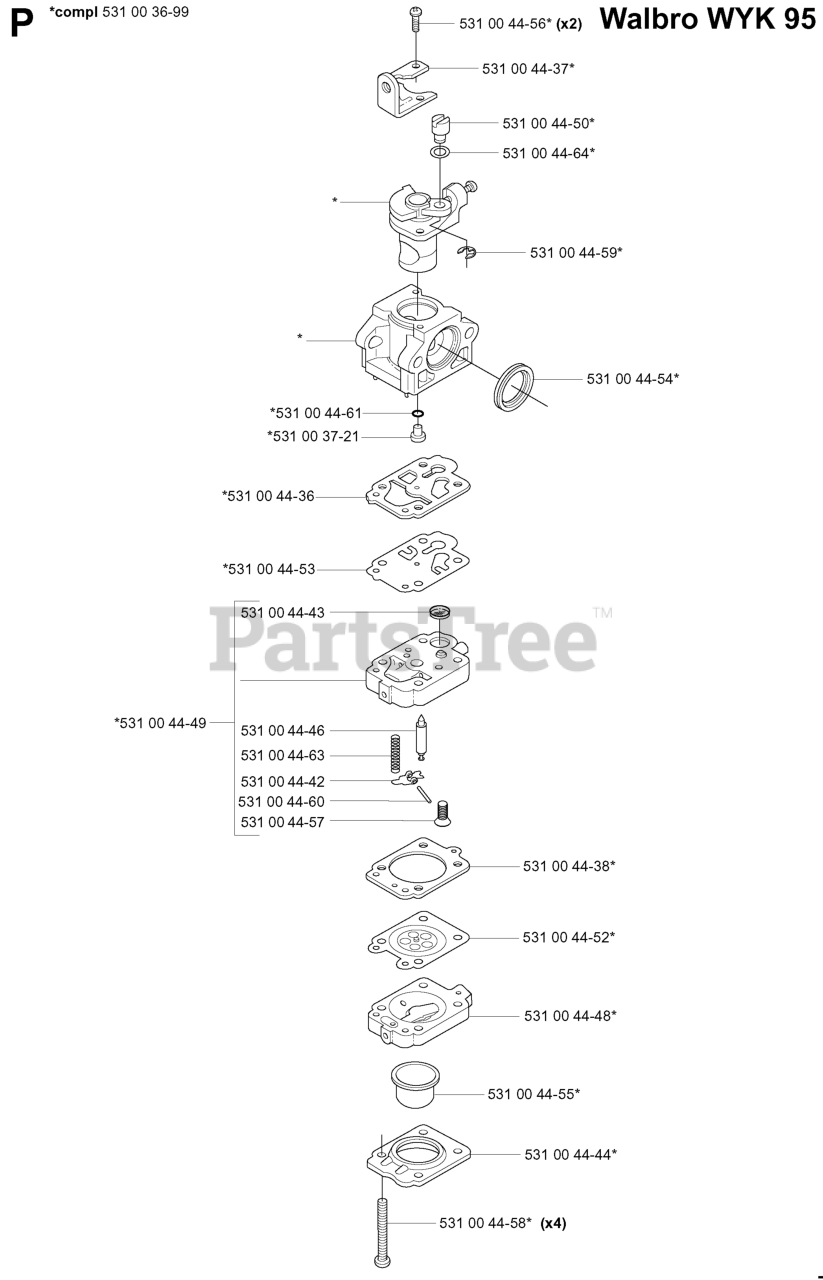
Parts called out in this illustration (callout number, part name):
3	RP LOGO
5	DASH
14	HOOD.HUSQVARNA.LT.ORANGE
15	LENS.HUSQVARNA LT.LH
18	GRILLE.SVC.HUSQVARNA.LT.GREY
25	LENS.HUSQVARNA LT.RH
34	PLATE.ENGINE.WELDED.CHASSIS
36	SCREW 5/16"
37	FENDER.TLT.FS.W/CUPHLD.ORANGE
52	LOCKNUT
58	DRAWBAR UPPER 2PC SMALL FENDER
68	Screw 5/16-18 x 1/2 Hex, Self Tapping 5/16-18 x 1/2
130	SCREW.#10 X 0.750.BOS
137	BUMPER DASH
151	BRACKET PIVOT
152	SHIELD.BROWNING.W/TEX
159	SCREW, 3/8-16X3/4
162	SCREW.HI-LO.CONSOLE
175	CROSSMEMBER
176	SCREW.#10-24X5/8.RN.QU
177	BUSHING STEERING
180	CHASS.WLDMNT.TL.12GA/2P.48/54
182	DASH.LOWER.PREDATOR LT
183	BOLT.5/16-18X1-1/4 FULL THD
189	SCREW
191	INSERT REFLECTIVE
194	NUT LOCK HEX FLANGE 5/16-18
199	PLATE.DECK.LIFT.HUSQ.LT
202	VENT SIDE HOOD LH
203	VENT SIDE HOOD RH
204	VENT TOP HOOD
205	SKIRT SIDE RH
206	SKIRT SIDE LH
213	BOLT
214	CLIP.RETAINER.TINNER.
217	ROD.PIVOT.HOOD
218	X-PIECE.HOOD.STOP.NON/
228	STUD.FASTNER.W/ANTI-ROTATE
234	BUMPER.HOOD.TEX.HUSQVARNA
235	SPACER FENDER
236	NUT.CENTERLOCK.5/16-
238	TRIM
282	CLIP.RETAINER.CONSOLE.LT.HUSQ
283	CONSOLE.ASM.LFT.NFR.HUSQ.LT
285	CONSOLE INSERT RH
286	CONSOLE.INSRT.LH.HUSQ.LT.BLACK
287	SCREW 1/4X20
297	INSERT.REFLECTIVE.RH.
